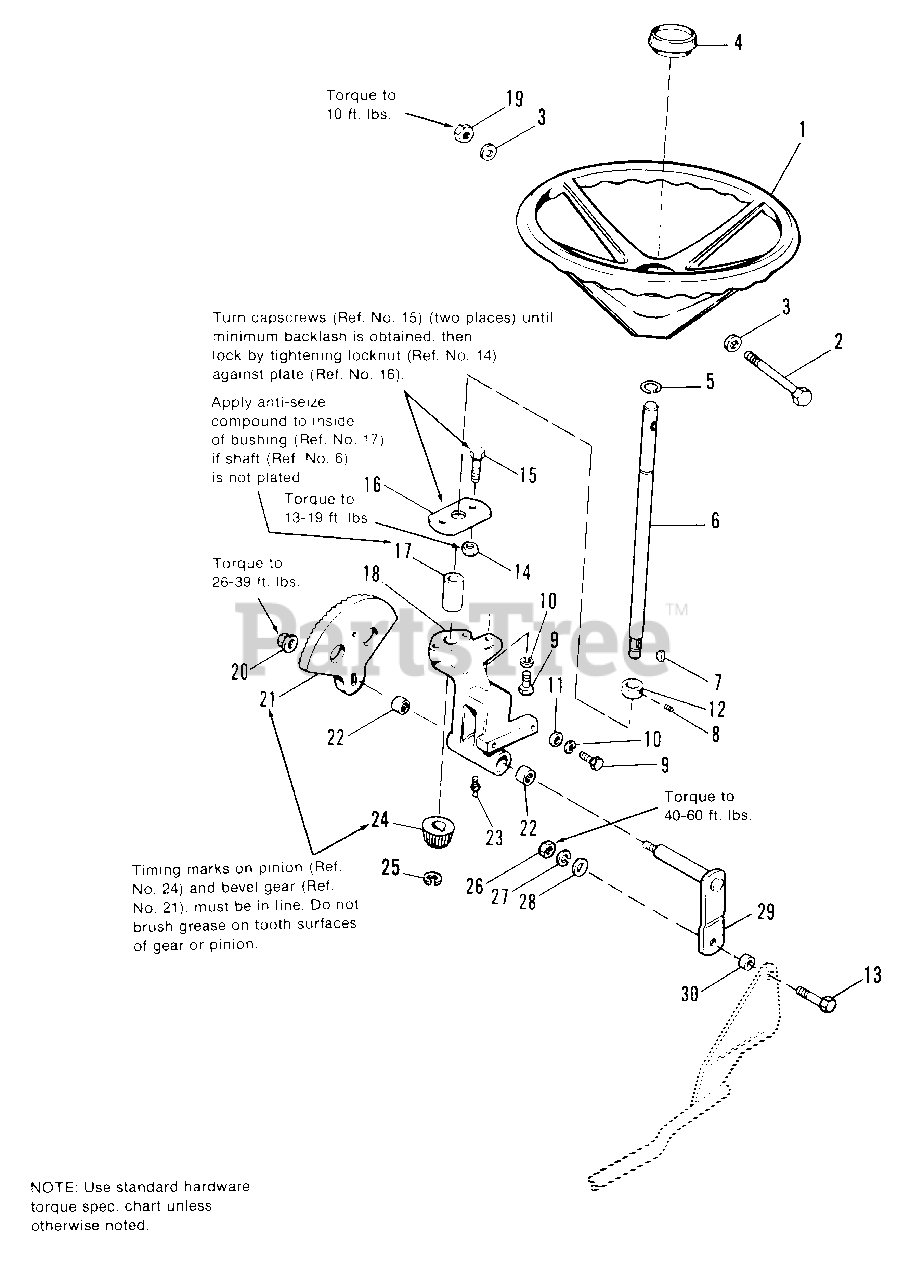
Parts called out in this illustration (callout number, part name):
1	WHEEL, Steering
2	BOLT, Hex, 5/16 x 3-1/2
3	WASHER, 5/16
4	CAP, Steering Wheel
5	RING, Retaining
6	SHAFT, Steering
7	KEY, Woodruff, #6
8	SETSCREW, 5/16-18 x 1/4
9	CAPSCREW, Hex Hd., 3/8-16 x 7/8
10	LOCKWASHER, 3/8
11	WASHER, Bevel, 3/8
12	COLLAR, Set
13	CAPSCREW, Hex Hd., 1/2-13 x 1-1/2
14	LOC KNUT, Hex, Jam 3/8-16
15	CAPSCREW, Hex Hd., 3/8-16 x 1-1/4
16	PLATE, Steering
18	HOUSING ASSY., Steering (Incl. Ref. No. 22)
19	LOCKNUT, Hex, Cntr. 5/16-18
20	LOCKNUT, Hex, Flange, 7/16-14
21	GEAR, Bevel
22	BEARING, Needle
23	FITTING, Grease
24	PINION, Bevel
25	E-RING
26	NUT, Hex, Full, 1/2-13
27	LOCKWASHER, 1/2
28	WASHER, Plain, 1/2
29	ARM ASSY., Steering
